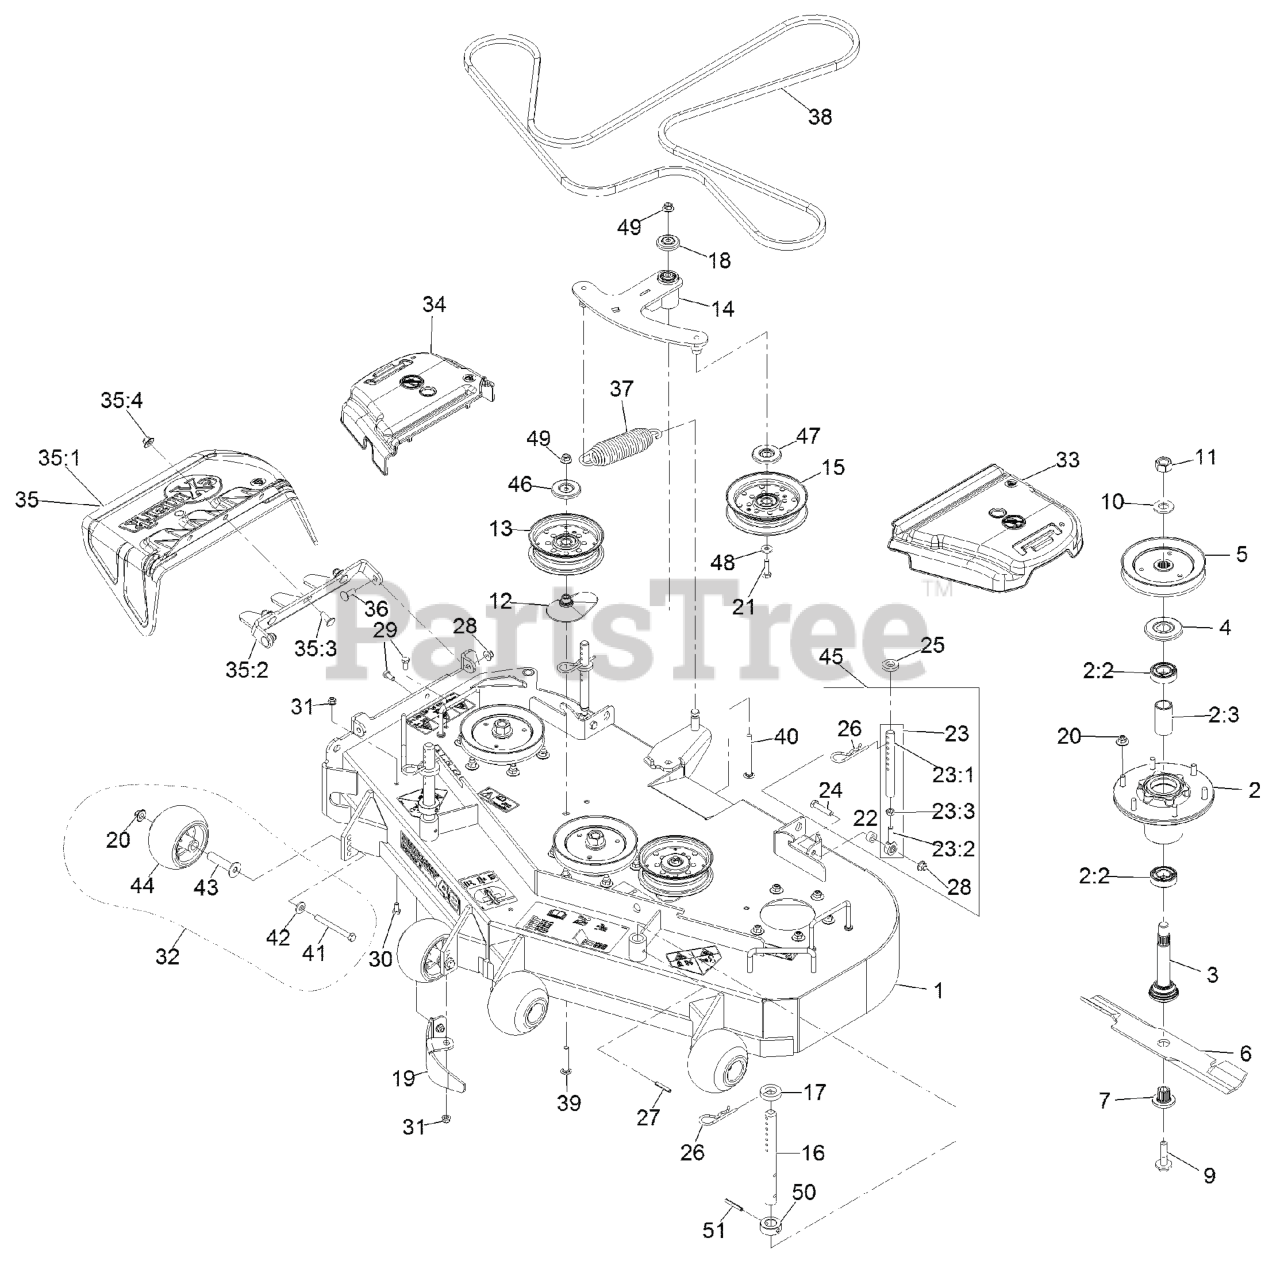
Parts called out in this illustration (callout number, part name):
1	ASM, DECK 48" W/DECALS
2	ASM-CUTTER HSG WITH BEARINGS
2:2	BEARING-BALL
2:3	SPACER-BEARING
3	ASM-SPINDLE AND SEAL
4	GUARD,BEARING TOP .989
5	SHEAVE,BLADE DRIVE 5.90
7	BUSHING,SPLINED
9	SCREW,SEMS 1/2-20 X 2.19
11	NUT-HEX
12	SPACER-PULLEY
13	IDLER-PULLEY, FLAT 5.00X1
14	ASM, DECK IDLER
15	IDLER-PULLEY, FLAT
16	Rod, Deck Support
17	SPACER-DECK SUPPORT
18	GUARD-TOP
19	BAFFLE, DOGLEG
20	Nut-Nyloc 3/8-16 Flg
21	SCREW-HH
23:1	LINK,SUPPORT
23:2	BALLJOINT
23:3	NUT-HJ
24	SCREW-HH
26	PIN,HAIR COTTER
28	NUT-HF, NI
29	SCREW-HH
30	SCREW-HH
31	NUT-HF, NI
32	KIT, ANTI-SCALP ROLLER
33	COVER-BELT, LH
34	COVER-BELT, RH
35	ASM, DISCHARGE CHUTE
35:1	CHUTE,DISCHARGE
35:2	BRACKET, DISCHARGE CHUTE
35:3	SCREW-CARR
35:4	Nut-Nyloc 3/8-16 Flg
36	SCREW-CARR
37	SPRING-EXTENSION
38	BELT, DECK
39	BOLT-CARR, SHORT NECK
40	SCREW-CARR
41	SCREW-HH 3/8-16 X 3 3/4 GR 8
42	WASHER-BELLEVILLE
43	AXLE, ROLLER
44	ROLLER-SCALP, ANTI
45	KIT,SUPPORT LINK W/PIN
46	SHIELD-DUST
47	SHIELD-GUARD, DUST
50	Collar, Deck Height Pin
51	PIN-ROLL
